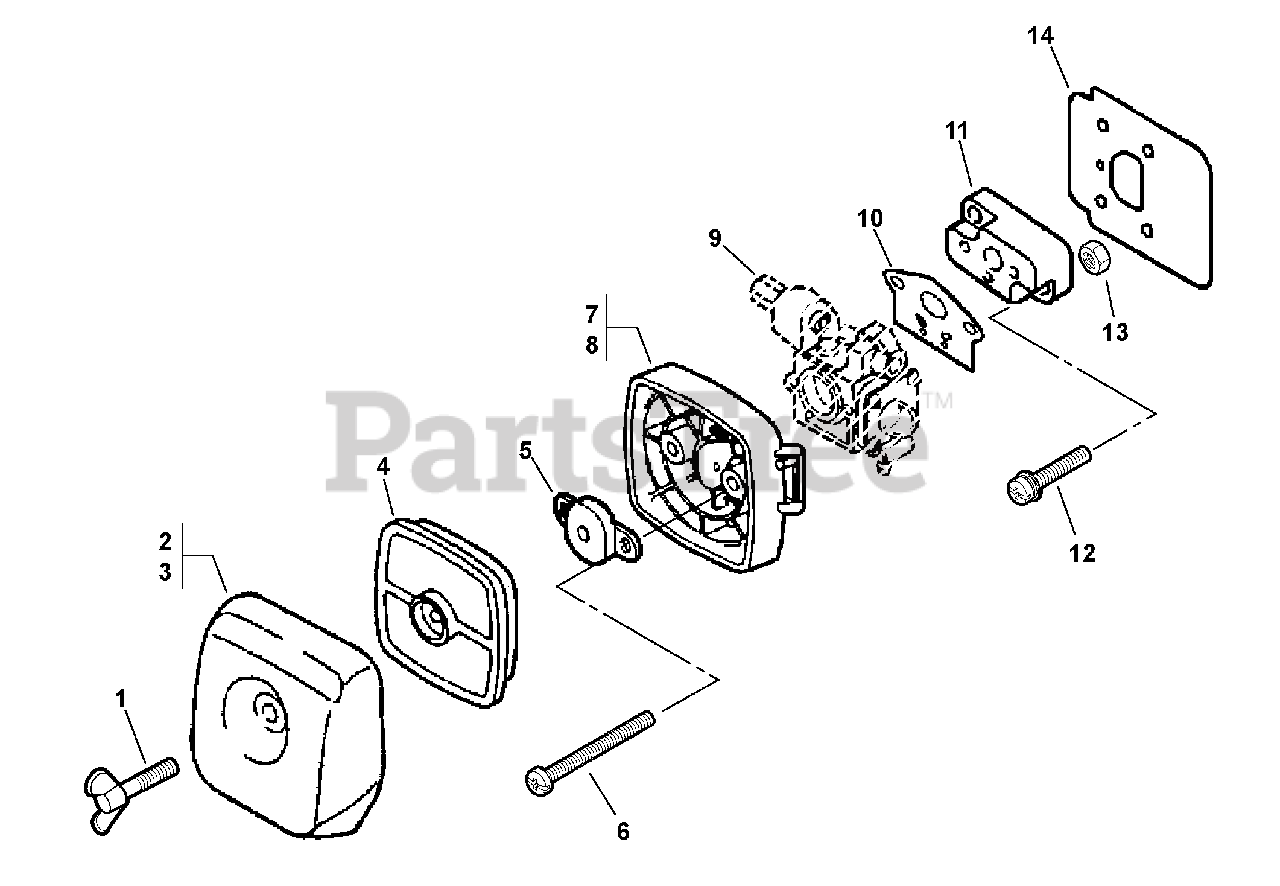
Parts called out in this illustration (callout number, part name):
1	Wing Bolt
2	Lid, Air Cleaner - Gray
3	Lid, Air Cleaner - Black
4	Filter, Air
5	Plate, Prevent
6	Screw 5x65
7	Case, Air Cleaner - Gray
8	Case, Air Cleaner - Black
9	Carburetor
10	Gasket, Intake
11	Insulator, Intake
12	Screw 5x20
14	Shield, Intake
